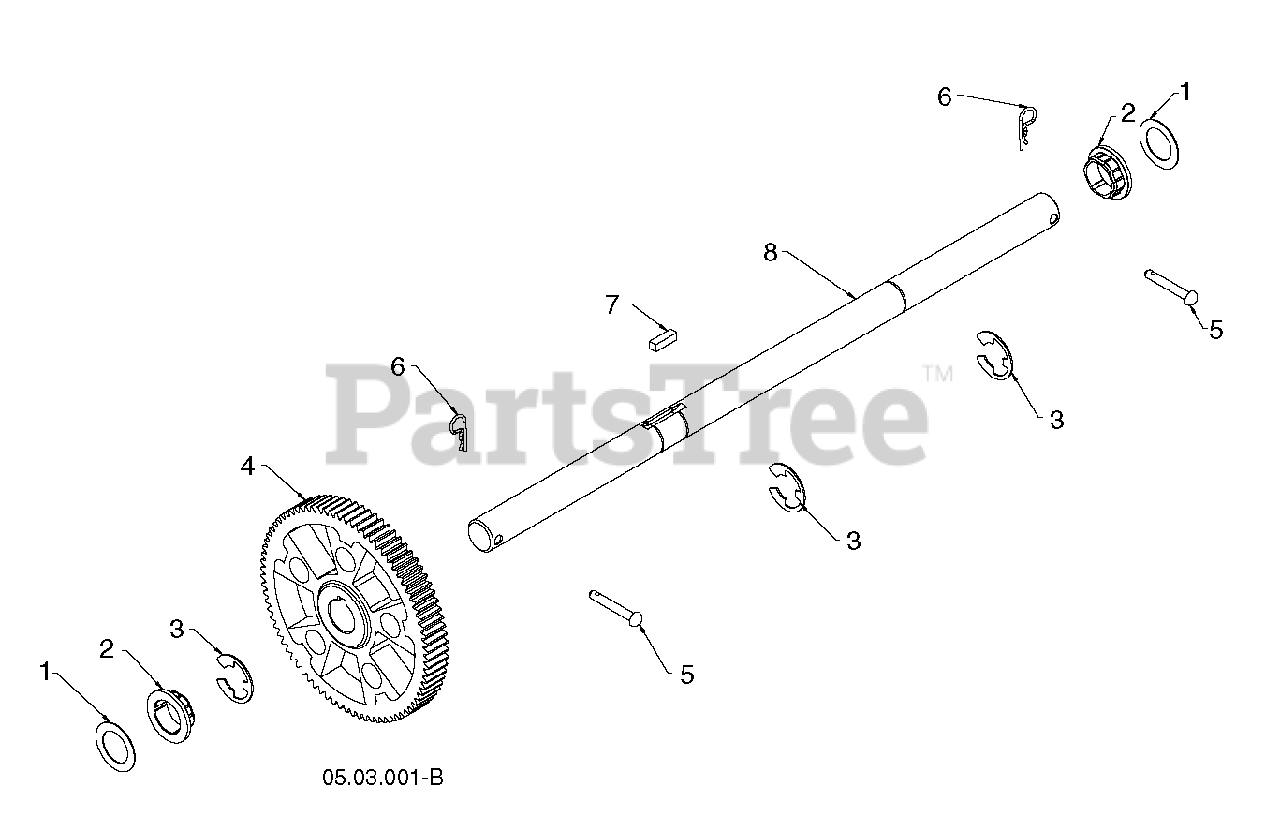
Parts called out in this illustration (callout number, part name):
1	WASHER 1.00
2	BUSHING.HEX.1.SHAFT
3	E RING HYT
4	GEAR.80T.DRIVEN.2PC
5	RIVET
6	RETAINER M
7	KEY, SQUARE 1/4 X .875
8	SHAFT SHAFT,AXLE,
